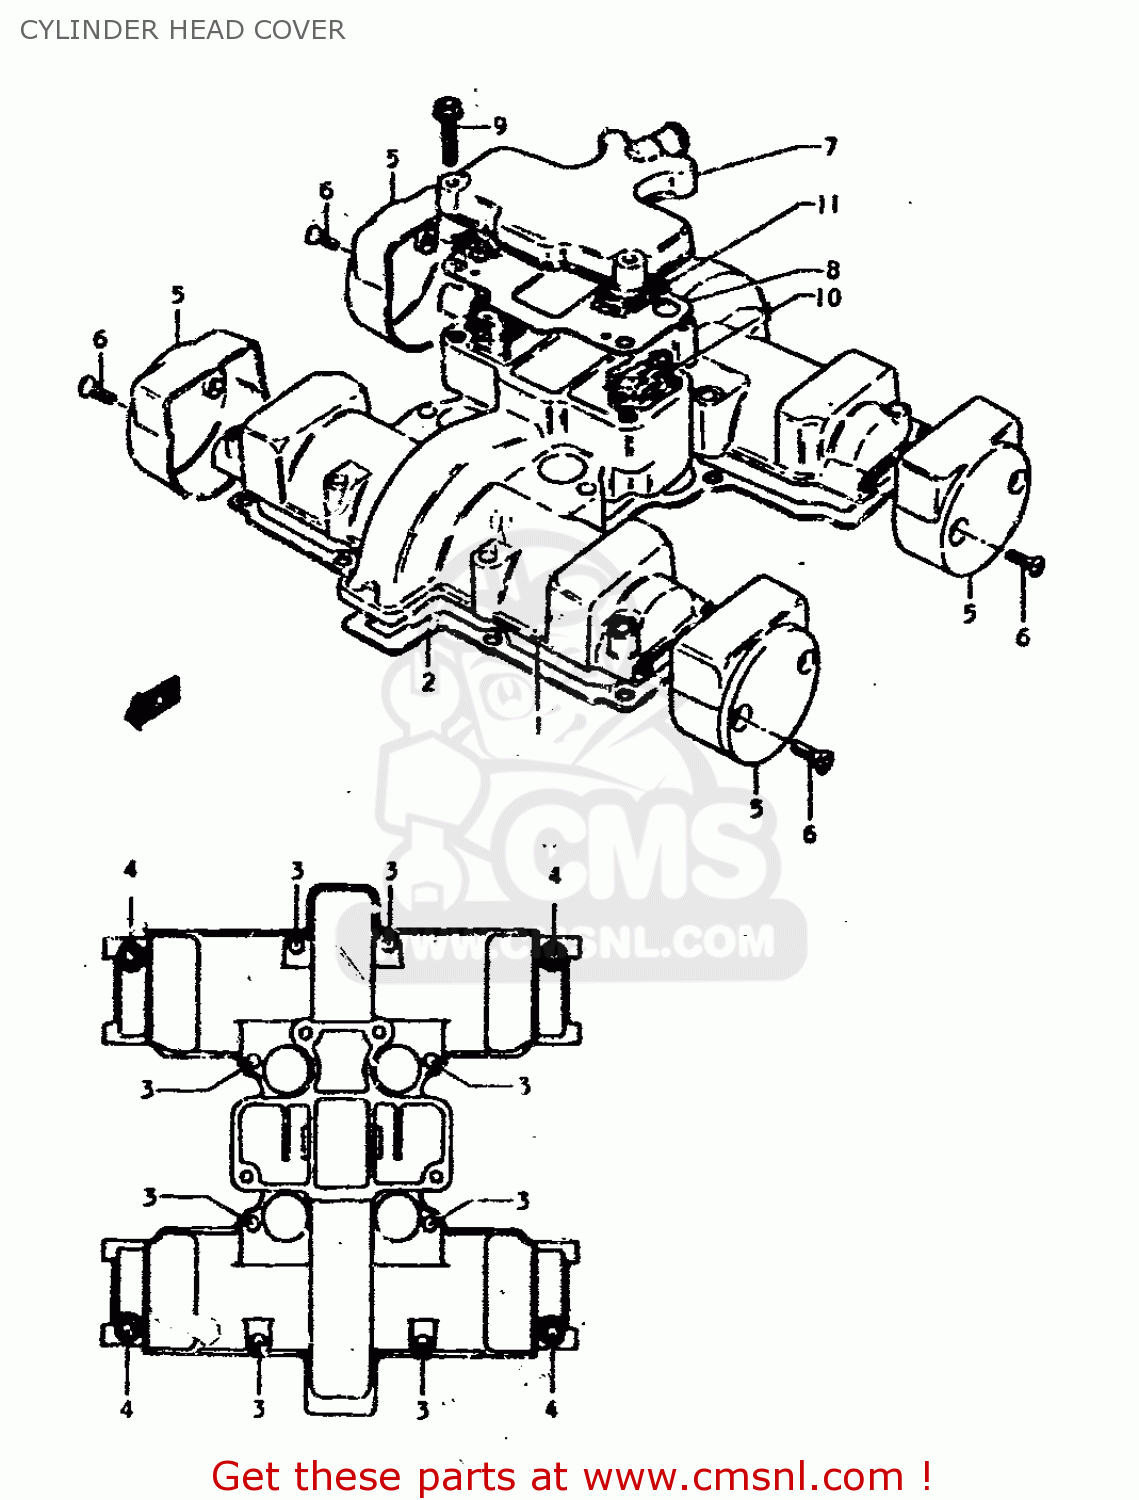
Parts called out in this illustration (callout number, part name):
1	COVER,CYLINDER HEAD
2	GASKET,CYLINDER HEAD COVER (MCA)
3	BOLT
4	BOLT
5	CAP,CYLINDER HEAD COVER
6	SCREW
7	COVER,BREATHER
8	GASKET (MCA)
9	BOLT
10	COVER,BREATHER
11	SEPARATOR,OIL BREATHER
